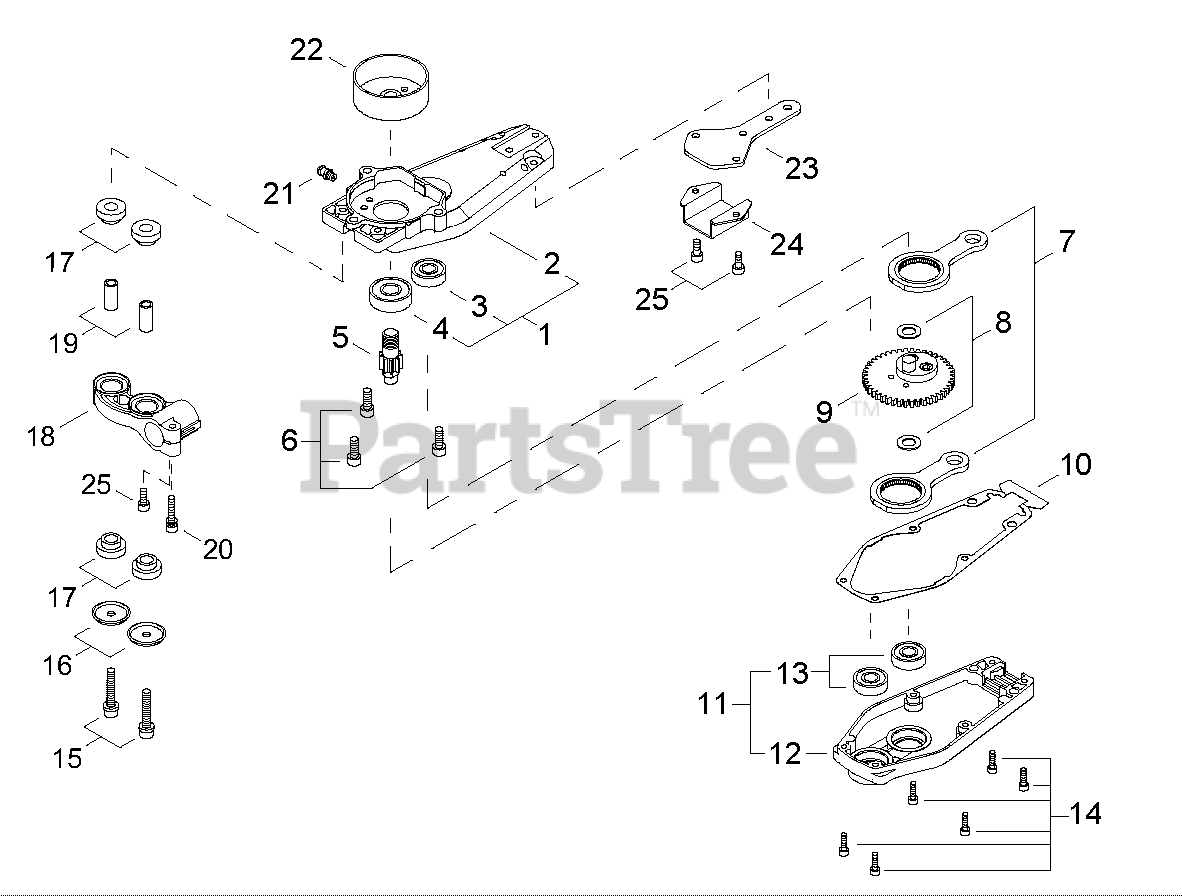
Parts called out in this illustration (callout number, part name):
1	GEAR CASE ASSY
2	CASE, GEAR
3	BEARING, BALL - 6000ZZ
4	BEARING, BALL - 6201
5	SHAFT, PINION
6	SCREW - 6X16
7	ROD, CONNECTING
8	WASHER - 10
9	CAM GEAR ASSY
10	GASKET, GEAR CASE
11	GEAR CASE LID ASSY
12	LID, GEAR CASE
13	BEARING, BALL - 6000ZZ
14	SCREW - 4X14
15	SCREW - 6X35
16	WASHER - CUP
17	CUSHION
18	MOUNT, HANDLE
19	COLLAR - 6
20	SCREW - 5X25
21	FITTING, GREASE
22	DRUM, CLUTCH
24	GUIDE, BLADE
25	SCREW - 5X12
